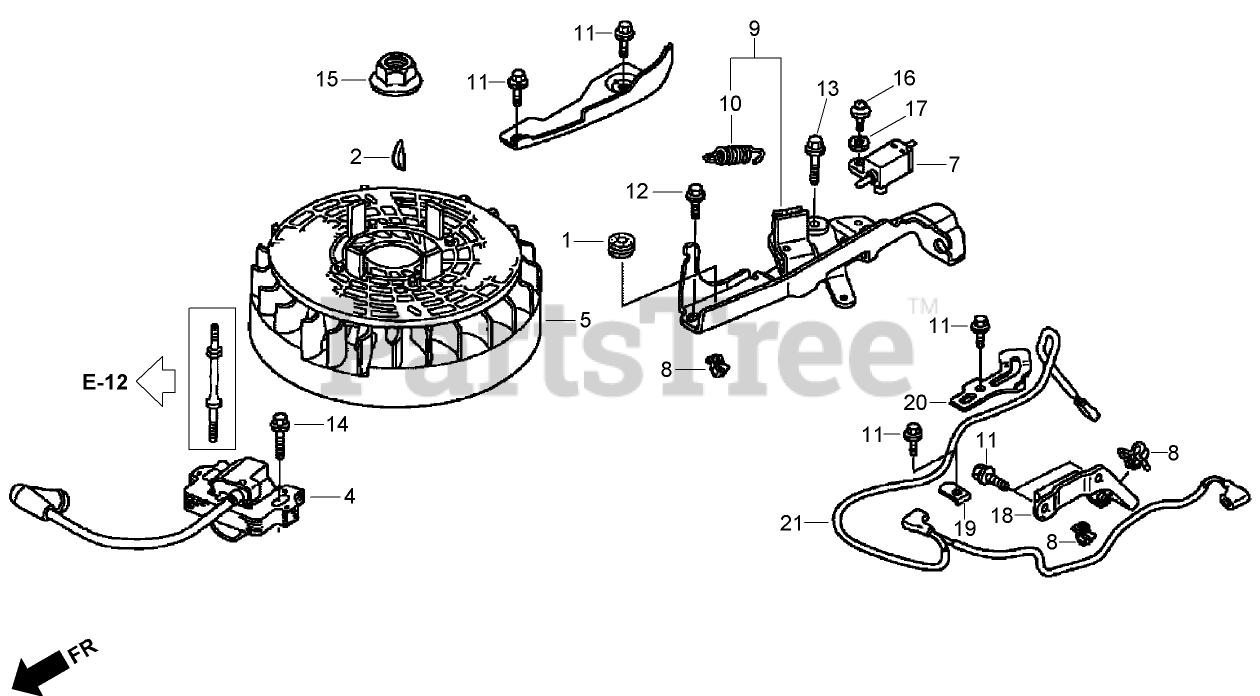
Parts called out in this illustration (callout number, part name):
1	GROMMET A-COVER, REAR (8X16X6.6)
1	GROMMET A, RR COVER (8X16X8)
2	KEY-WOODRUFF, SPECIAL (25X18)
4	IGNITION COIL ASM (PHELON) (USE FOR FLYWHEEL OF PHELON)
5	FLYWHEEL ASM (PHELON) (USE FOR IGNITION COIL OF PHELON)
7	ENGINE STOP SWITCH ASM (N C)
8	HOLDER-WIRE (FASTEX)
8	CLIP A-CABLE (3.8MM BLACK) (NIFCO)
9	BRAKE ASM
10	SPRING-LEVER, BRAKE
11	BOLT-FLANGE (6X12) (C T200)
12	BOLT-FLANGE (6X14) (C T200)
13	BOLT-FLANGE (6X23) (C T200)
14	BOLT-FLANGE (6X20) (C T200)
15	NUT-FLANGE (14MM)
16	SCREW-WASHER (4X12)
17	WASHER-PLAIN (4MM)
18	CLAMP-WIRE, STOP SWITCH
19	CLAMP-WIRE, STOP SWITCH
20	CLAMP-WIRE
21	WIRE-SWITCH, STOP
